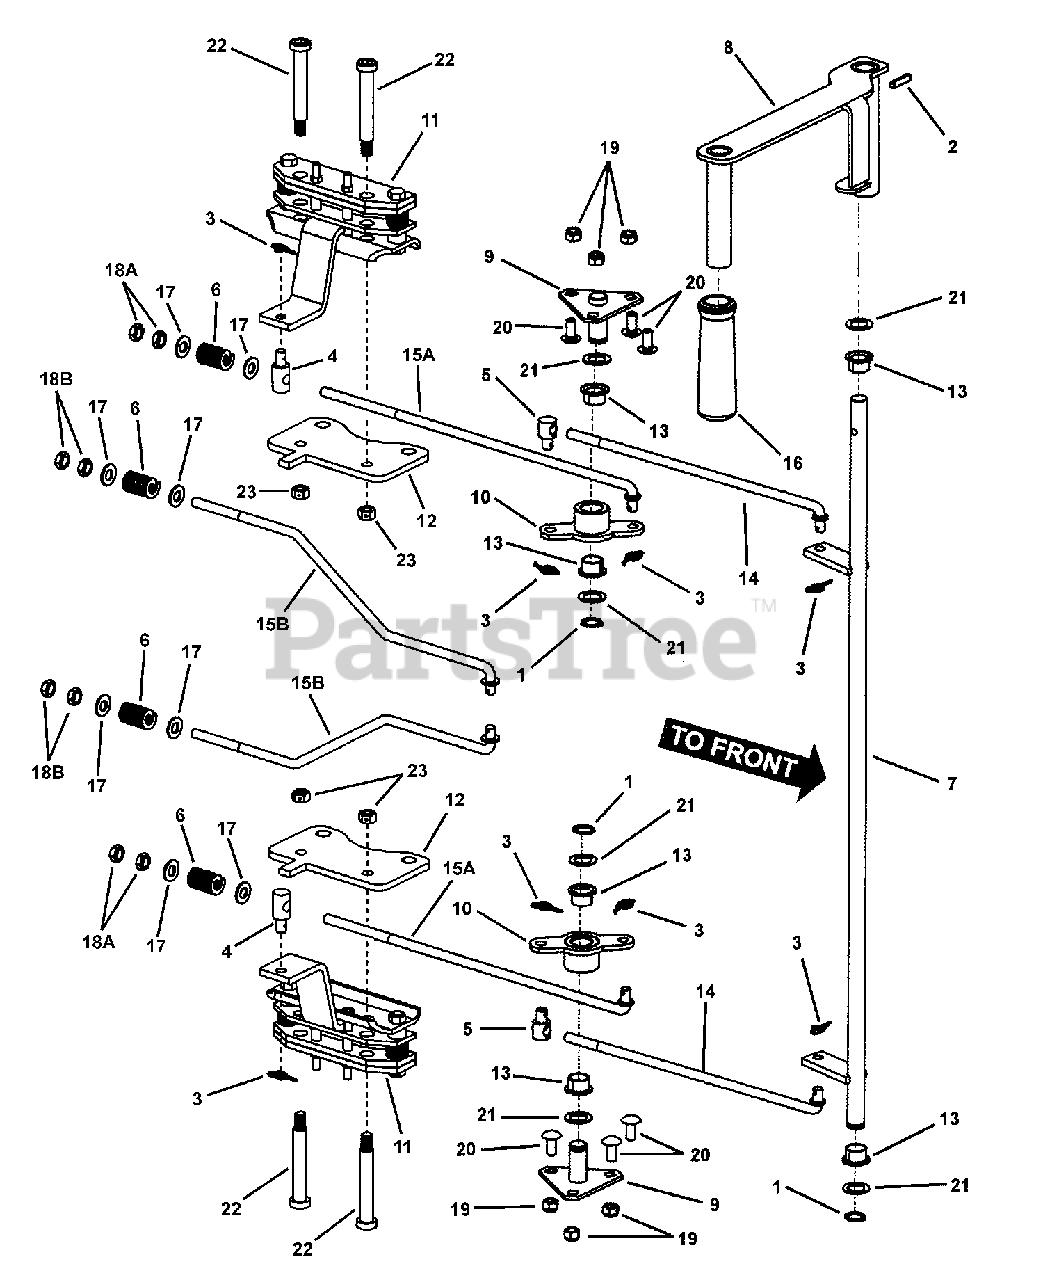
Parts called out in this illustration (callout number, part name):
1	RING, 5/8" External Retaining
2	GROOVE PIN, 1/4 x 1-1/4" long
3	PIN, 3/8" Self Locking Cotter
4	SWIVEL, 3/8" Thru Hole, Special
5	SWIVEL, 3/8-24 Adjustment
6	SPRING, Rectangular Wire Die, Blue
7	WELDMENT, Brake Rod Crossrod
8	WELDMENT, Park Brake Handle
9	WELDMENT, Brake Linkage Pivot
10	WELDMENT, Brake Linkage Bellcrank
11	ASSEMBLY, Brake
12	BRACKET, Brake Mounting
13	BUSHING, Teflon Impregnated
14	FRONT LINKAGE, Park Brake (3/8-24 thread)
15A	REAR LINKAGE, Park Brake (3/8-24 thread)
15B	ROD, Brake Rear (3/8-16 thread)
16	GRIP, Parking Brake
17	WASHER, 3/8" SAE Flat
18A	NUT, 3/8-24, Hex Jam, GR 5 or B
18B	NUT, 3/8-16, Hex Jam, GR 5 or B
19	NUT, 5/16-18 Hex Nyloc
20	BOLT, 5/16-18 x 3/4" Short Neck Carriage, GR 5
21	WASHER, .64 I.D. x .99 O.D. x .05 Flat
22	SHOULDER BOLT, 3/8-16 Hex Socket Head
23	NUT, 3/8-16 Hex Center Lock
